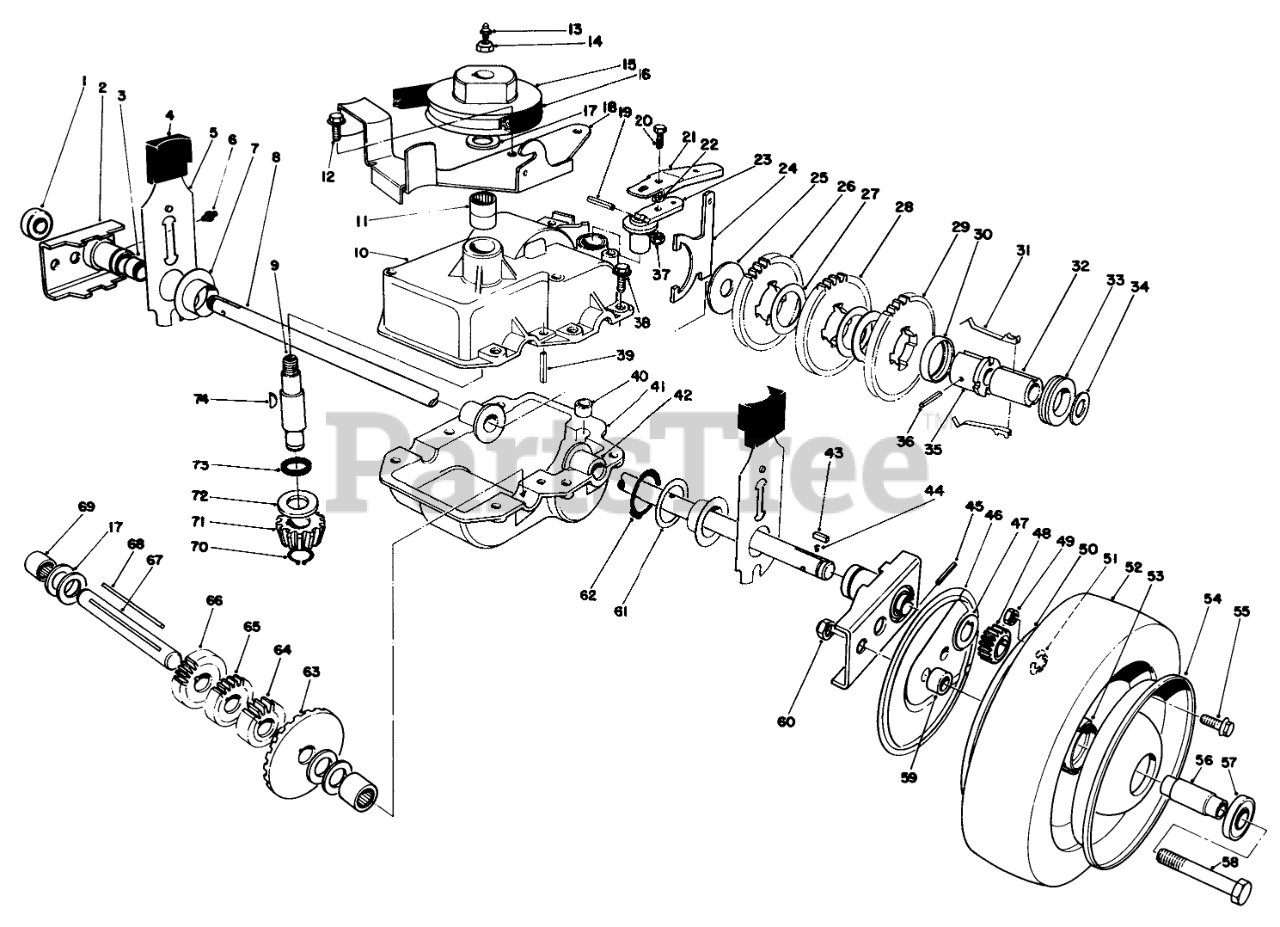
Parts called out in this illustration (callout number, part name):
1	Ball Bearing
2	Pivot Arm Assembly (Incl. Ref. #1, 3 & 6)
3	BUSHING
4	KNOB-ARM
5	Spring Arm Assembly-Rear
6	FITTING-GREASE
7	CAP-END
8	Shaft-Output
9	Shaft Input
10	Upper Case Assembly (Incl. Ref.#11 & 73)
11	BEARING-NEEDLE
12	SCREW
13	FITTING-GREASE
14	NUT-HEX
15	PULLEY
16	V-BELT
17	WASHER-THRUST
18	Belt Guide Bracket
19	PIN-COIL
21	SHIFT LEVER COVER
22	WASHER-FLAT
23	LEVER-SHIFT
24	Shift Yoke
25	WASHER
26	GEAR-38T
27	WASHER
28	GEAR-42T
30	RETAINER-KEY
31	KEY-SHIFT
32	SLEEVE
33	COLLAR-SHIFT
34	WASHER-PLAIN
35	SLEEVE-GEAR
36	PIN-GROOVE
37	NUT-LOCK, NI
38	SCREW-HWHTF
39	ROLL PIN 3/16 X 1 IN
40	BUSHING-YOKE
41	Case-Lower
42	BUSHING
43	KEY RECTANGULAR
44	SPRING-COMPRESSION
45	Pin
46	WHEEL COVER
47	WASHER-THRUST, OUTER
48	GEAR-PINION
49	NUT-LOCK, NI
50	Wheel-Half
51	RING-RETAINING
53	HUB-BEARING
54	Wheel-Half
55	SCREW-HHF
56	SPACER-BEARING
57	BEARING-WHEEL
58	SCREW-HH
59	SPACER-WHEEL
60	NUT-LOCK, NI
62	RING-RETAINING
63	BEVEL GEAR
64	GEAR-12T
65	GEAR-14T
66	GEAR-18T
67	SHAFT-INTERMEDIATE
69	BEARING-NEEDLE, CLOSED
70	RING-RETAINING
71	PINION-BEVEL
72	WASHER-THRUST
74	KEY-WOODRUFF
